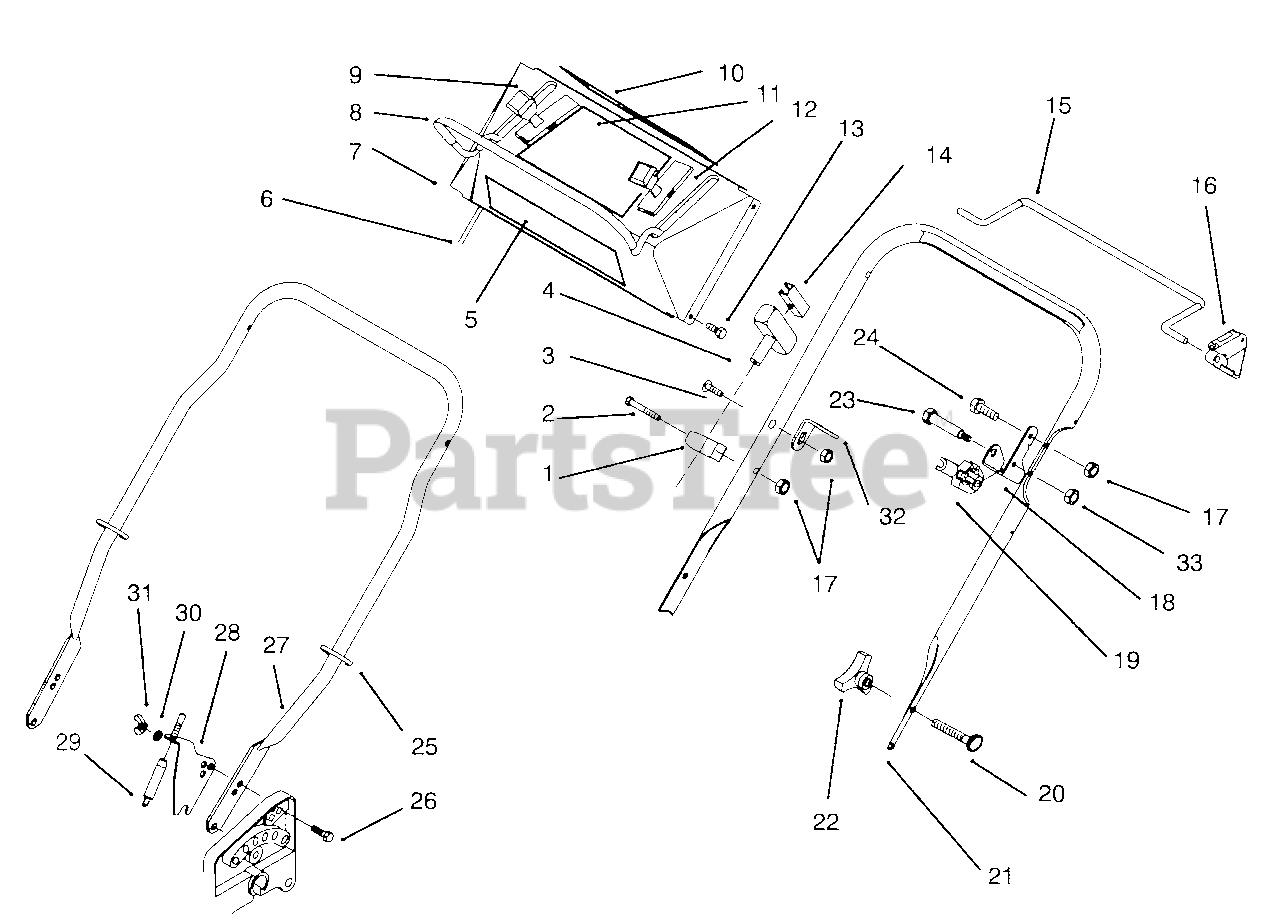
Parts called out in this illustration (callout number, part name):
1	Guide-Rope
4	Handle-Rope
5	Decal-Control Panel
6	Cable-Brake
7	Panel-Control (Incl. Ref. #10 & 11) (Hand Push)
8	Bail-BBC Brake
9	Control Ground (SeK Propelled)
10	Decal-Warning (English)
11	Decal-Control Panel, (Self Propelled English)
12	Control-Throttle
14	Insert-Handle
15	Bail-Control, (Self Propelled)
16	Stop-Pivot (Self Propelled)
18	Bracket-Cam
19	Brake-BBC Cam
20	Screw-Handle
21	Handle-Upper
22	Knob-Handle
23	Bolt-Shoulder
24	Screw-Hex. Hd.
25	Tie-Cable
26	Bolt-Carriage
27	Handle-Lower
28	Bracket-Traction Cable (Self Propelled)
29	Cable-Traction (Self Propelled)
32	Bracket-Cable
